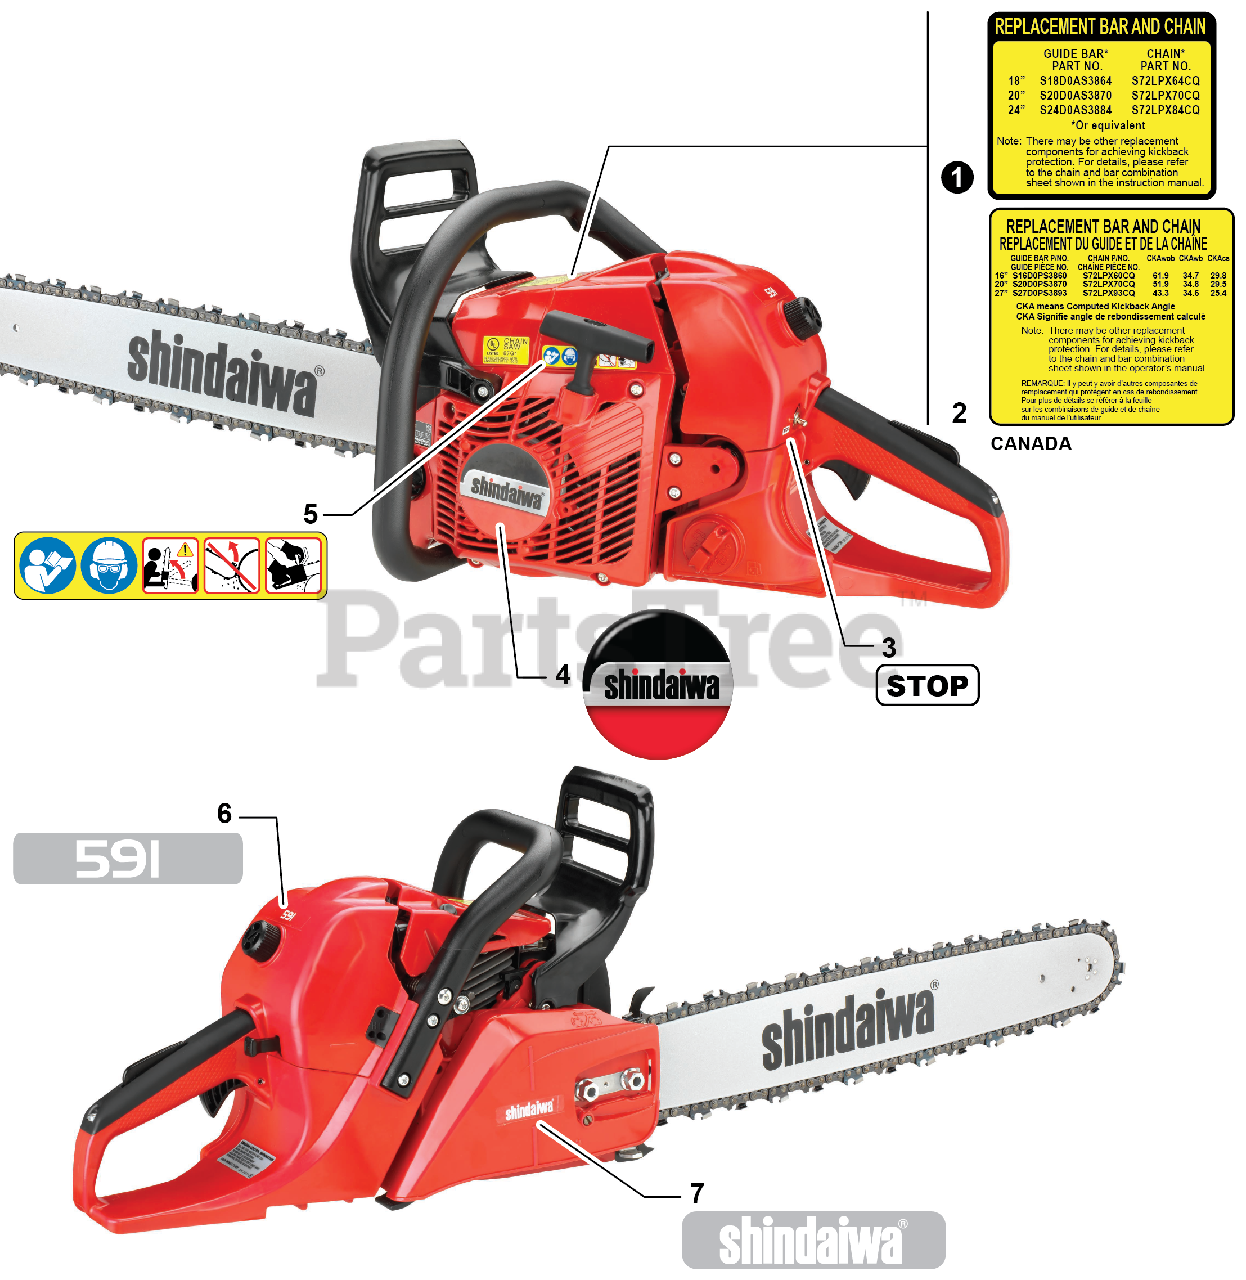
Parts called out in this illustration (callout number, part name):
1	LABEL, BAR & CHAIN
2	LABEL, BAR & CHAIN
3	LABEL, STOP
4	LABEL, STARTER - shindaiwa
5	LABEL, CAUTION
6	LABEL - MODEL 591
7	LABEL - shindaiwa
